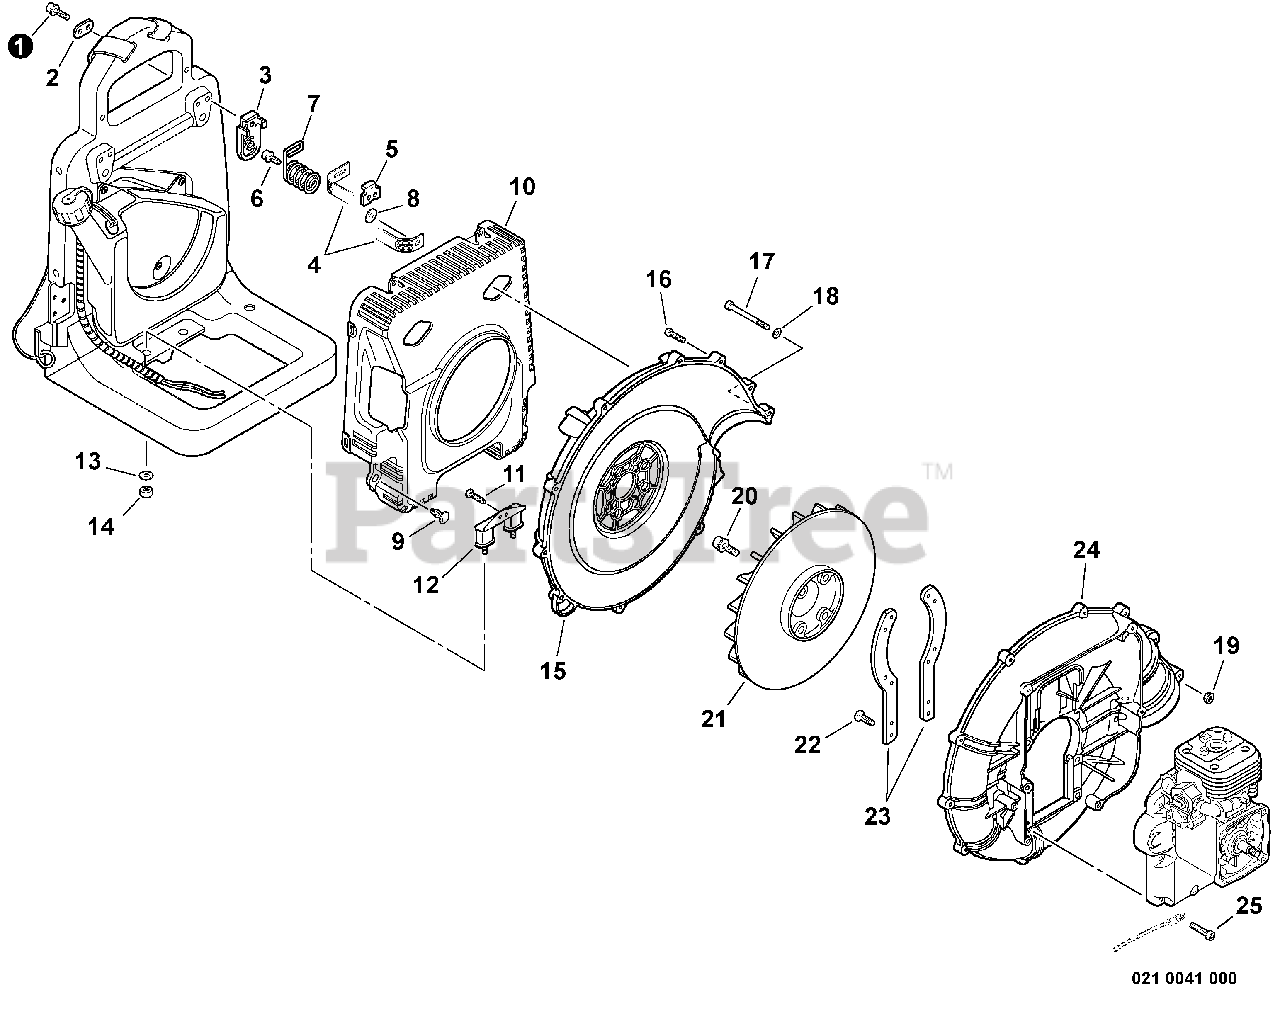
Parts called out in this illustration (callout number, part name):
1	SCREW - 5X20
3	BRACKET, SPRING
4	STRAP, SAFETY
5	RETAINER
6	SCREW - 5X20
8	WASHER - 5
10	GUARD, DEBRIS
11	SCREW - 5X16
12	CUSHION
13	WASHER - 5
14	NUT - 5 -- FLANGE
15	COVER, FAN - INNER
16	SCREW - 5X25 -- TAPPING
17	SCREW - 5X60
18	WASHER - 5
19	NUT - 5 -- FLANGE
20	SCREW - 5X20
22	SCREW - 3X12 -- TAPPING
23	BRACKET, ENGINE
24	COVER, FAN - OUTER
25	SCREW - 5X32
